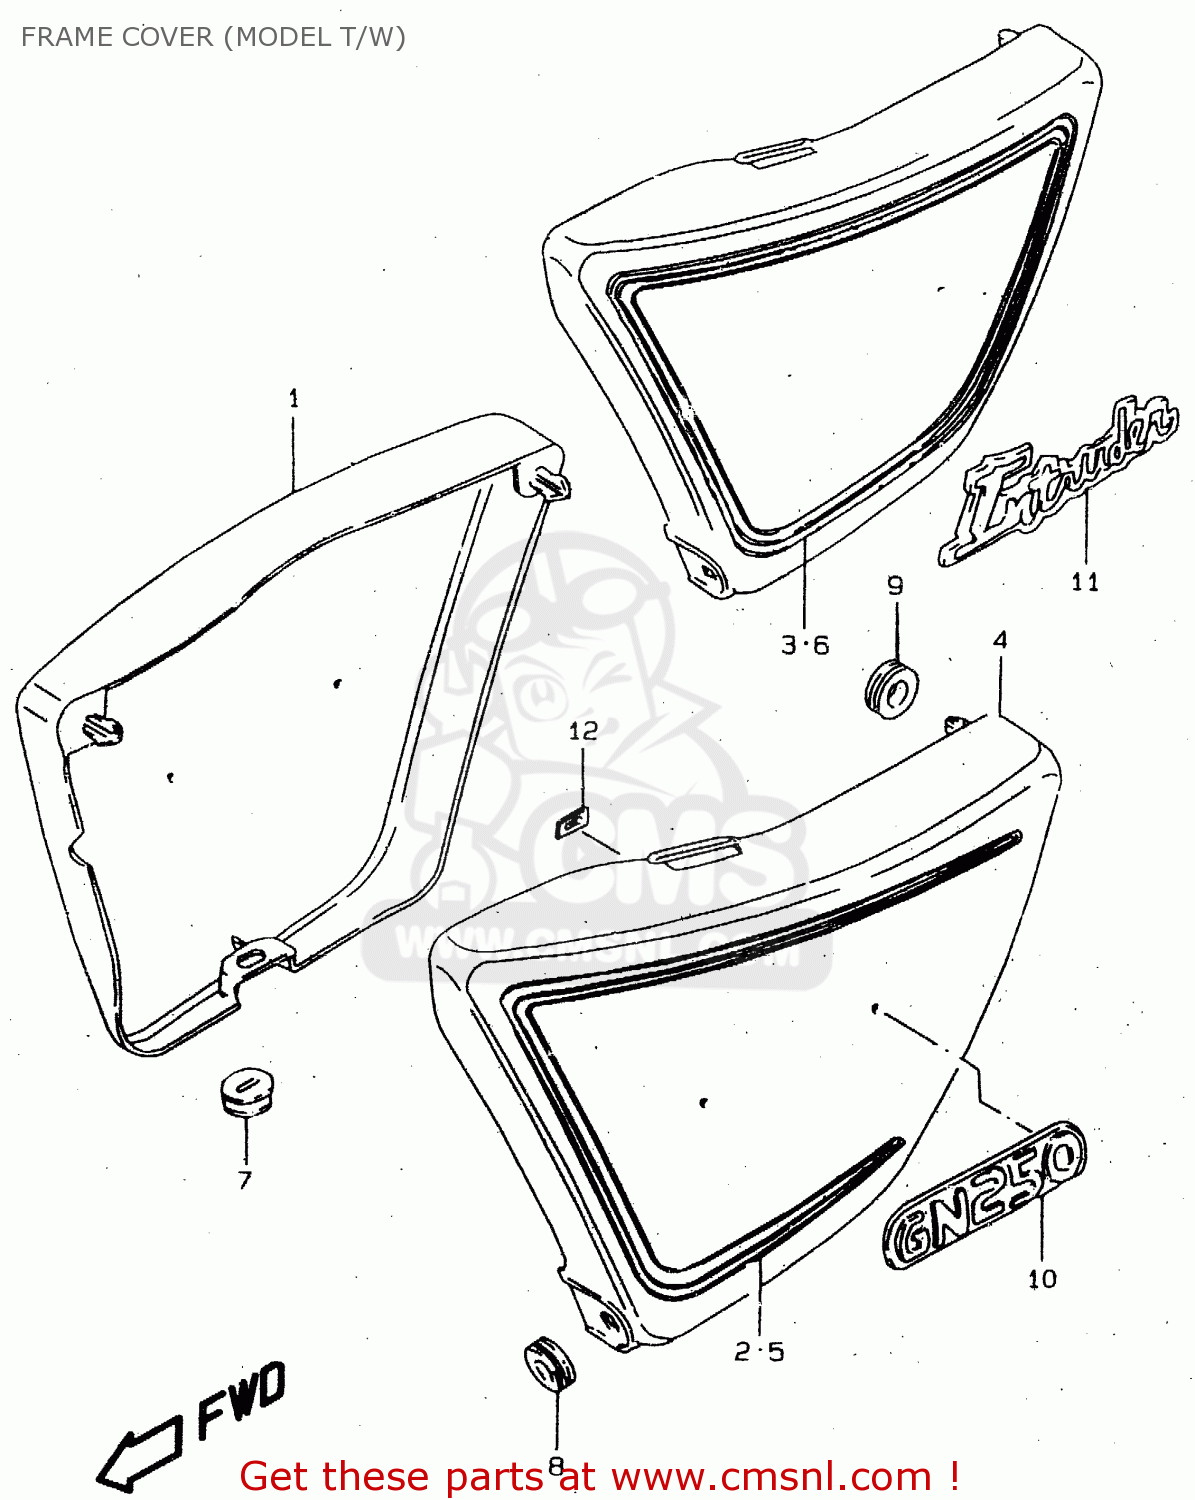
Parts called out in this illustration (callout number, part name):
1	COVER,FRAME,R(RED)
2	TAPE SET,FRAME COVER,R
3	TAPE SET, RH
4	COVER,FRAME,LEFT
5	TAPE SET,FRAME COVER,L
6	TAPE SET, LH
7	CUSHION
8	CUSHION
9	CUSHION
10	EMBLEM,GN250
11	EMBLEM,FRAME COVER
12	NUT
